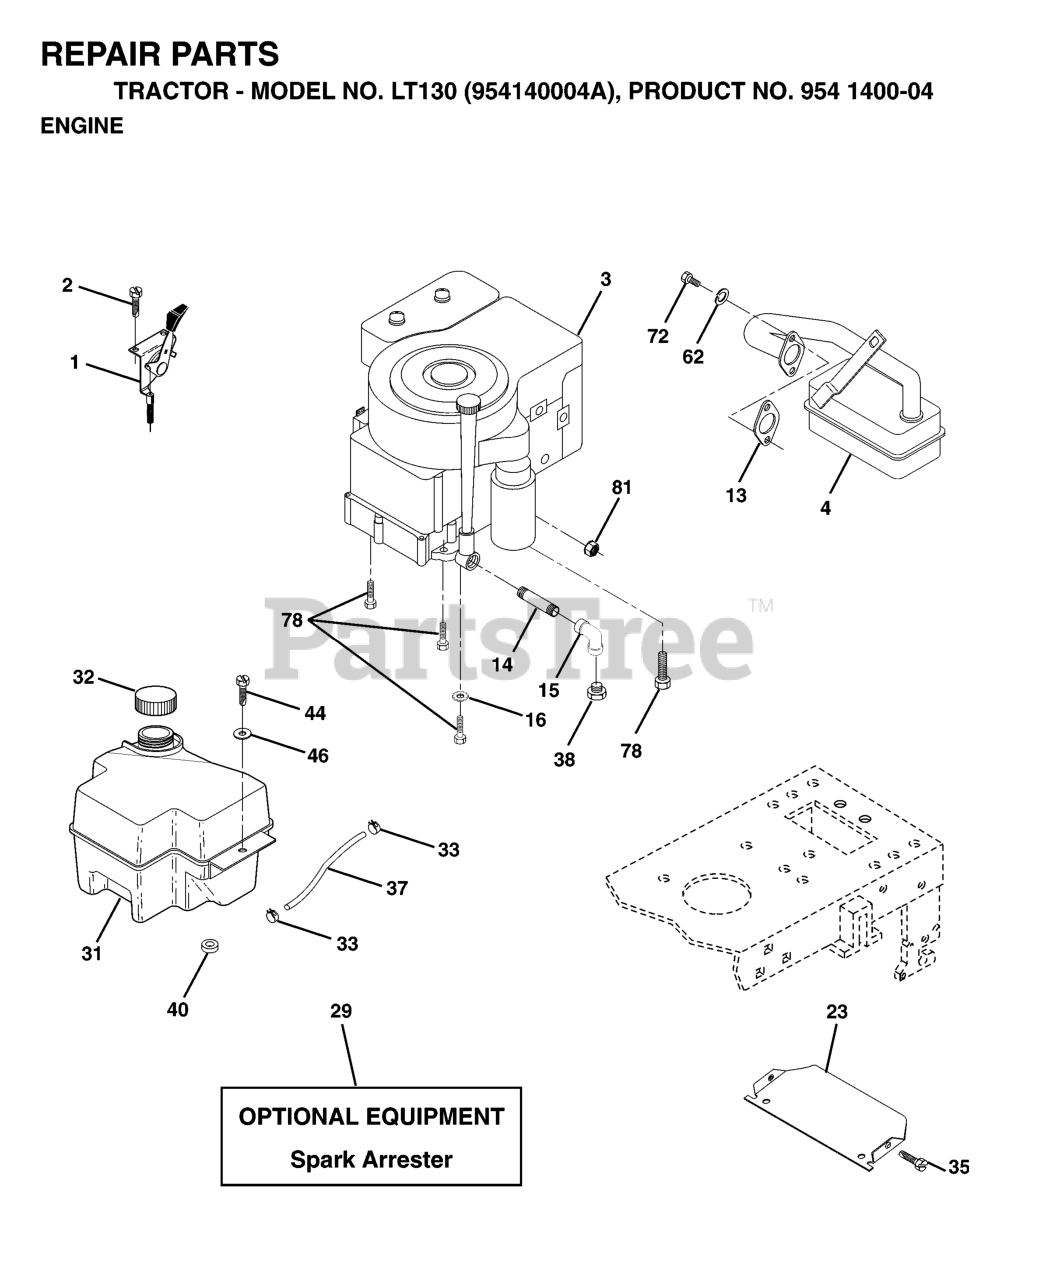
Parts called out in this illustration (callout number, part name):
1	CHOKE CONTROL
2	SCREW LT
4	MUFFLER.SINGLE.B&S.10-12HP
13	GASKET.ENG.1.313 ID.TIN PLATED
14	Nipple Pipe 3/8 Npt X 3-1/2
15	ELBOW
16	LOCKWASHER
23	SHIELD HEAT
29	KIT.SPARK ARRESTOR 794945 B&S
31	FUEL TANK
32	FUEL CAP
33	HOSE CLAMP
35	SCREW.THDROL.5/16-18X3/4.TTY
37	LINE.FUEL.20
40	BUSHING.SNAP.NYL.BLK.
44	SCREW HEX CRT
62	WASHER.LOCK.HVY.HLCL.SPR.5/16
72	SCREW
78	SCREW
81	NUT FLANGE 1/4-20 STARTER NUT
